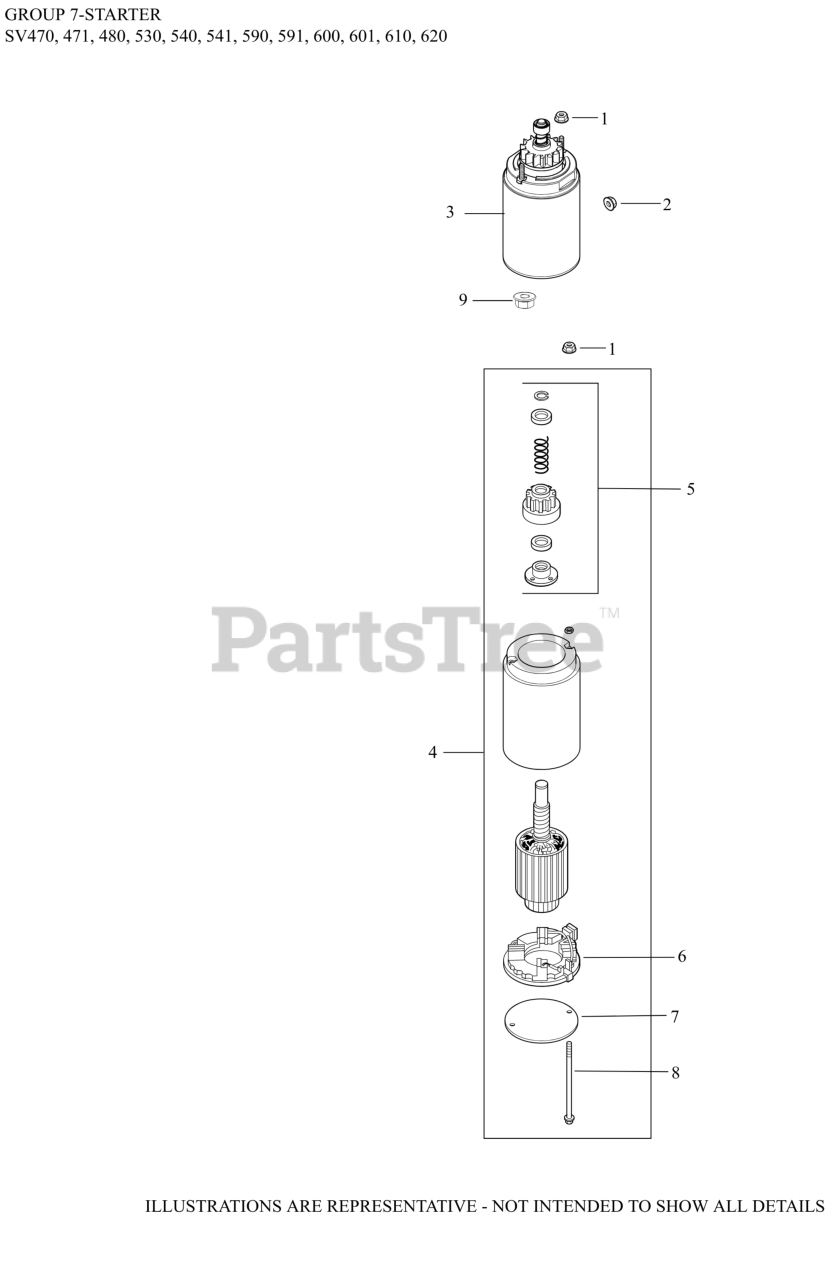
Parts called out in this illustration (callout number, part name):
1	NUT, HEX FLANGE LOCK (10-24)
2	NUT, FLANGE 1/4-20
3	STARTER, ASSY
